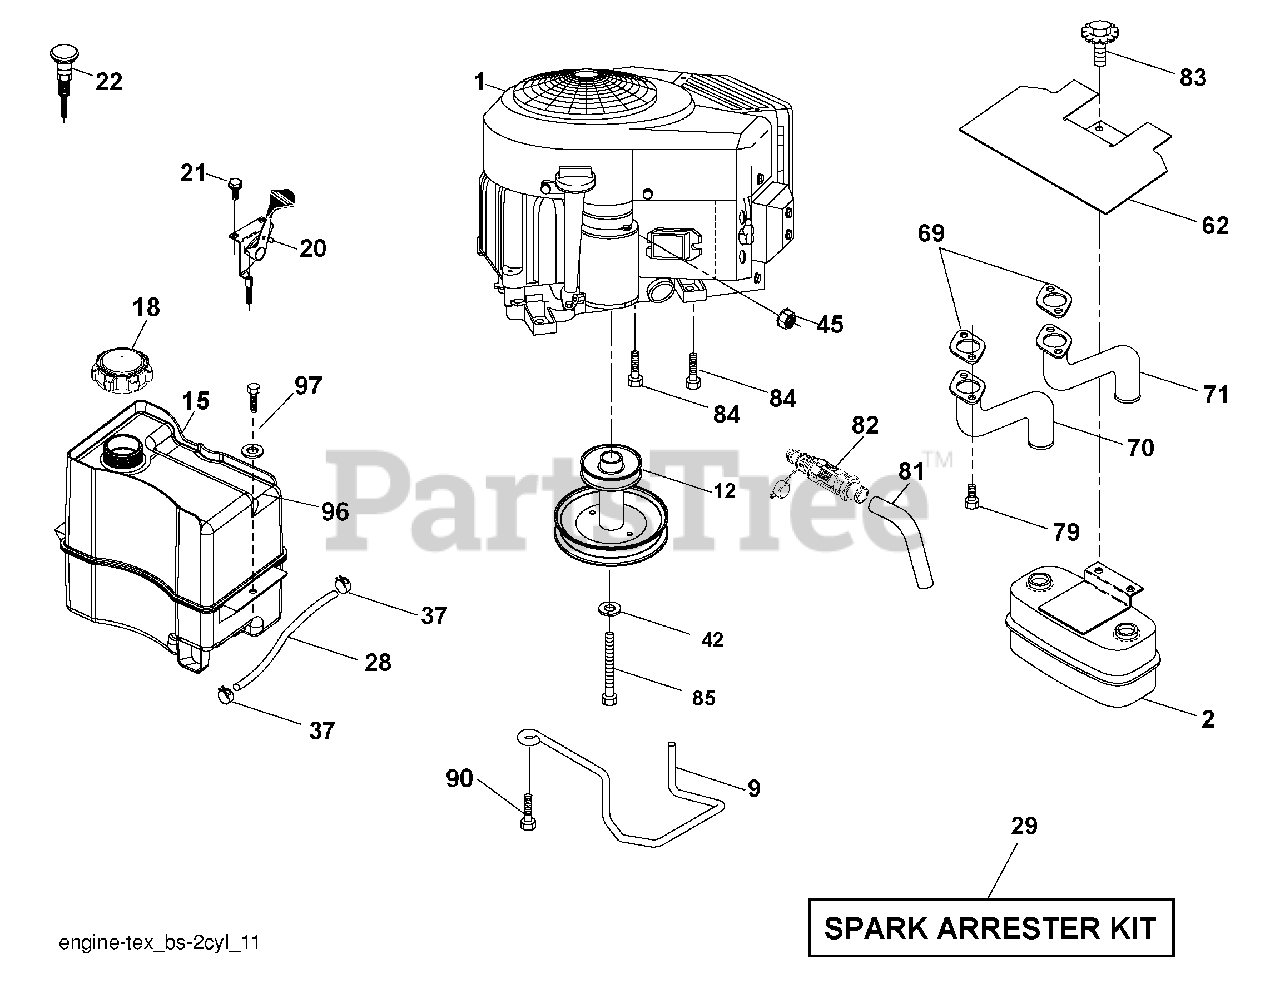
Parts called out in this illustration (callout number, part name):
9	Keeper Belt Engine
12	Pulley Engine
15	Tank Fuel
18	Cap Asm
20	Control Throttle
21	Screw #10 x 0.750 BOS Thread
22	Control Choke
28	Fuel Line
29	Spark Arrester Kit
37	Clamp Hose
42	Washer Lock 7/16
45	Nut Keps Hex 1/4-20 unc
62	Shield Heat
70	Exhaust Tube LH
71	Exhaust Tube RH
79	Screw 5/16-18 x 1
81	Tube Drain Oil Easy
82	Valve Drain Oil
83	Bolt 5/16-18 unc x 3/4 w/sems
84	Screw 3/8-16 x 1/4
85	Bolt Hex 7/16-20 x 4 Gr. 5
90	Screw 3/8-16 x 1
96	Washer 9/32 x 7/8 x 16 Ga.
97	Screw 1/4-20 x 3/4
